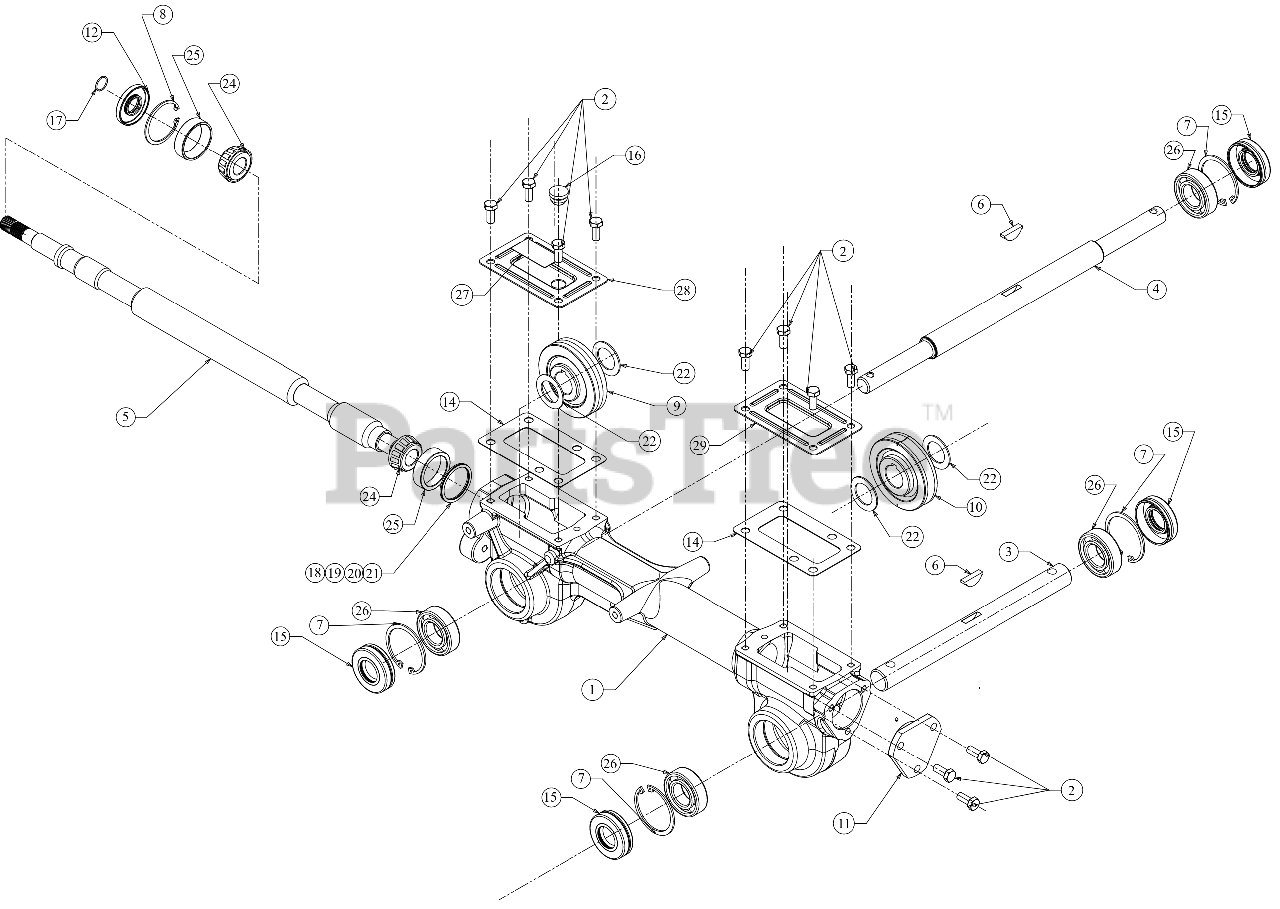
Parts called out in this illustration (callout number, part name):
1	HOUSING ASSEMBLY
2	SCREW 5/16-18 x .75 GR5
3	TILLER SHAFT
4	WHEEL SHAFT
5	WORM DRIVE SHAFT
6	KEY-HI PRO .25 X 1
7	RETAINING RING
8	RETAINING RING
9	WORM GEAR (RH) 61T
10	WORM GEAR (LH) 30T
11	BEARING COVER
12	OIL SEAL .750 SHF X 1.783
14	GEAR HOUSING GASKET
15	OIL SEAL 1.00 SHF X 2.00 BORE
16	RUBBER OIL PLUG
17	WIRE RING
18	FLAT WASHER 1.500X1.750X.062
19	FLAT WASHER 1.500X1.750X.005
20	FLAT WASHER 1.500X1.750X.030
21	FLAT WASHER 1.500X1.750X0.010
22	WASHER 1.010X1.560X.060
24	BEARING CONE
25	BEARING CUP
26	BALL BEARING
28	TRANSMISSION COVER
29	TRANSMISSION COVER
